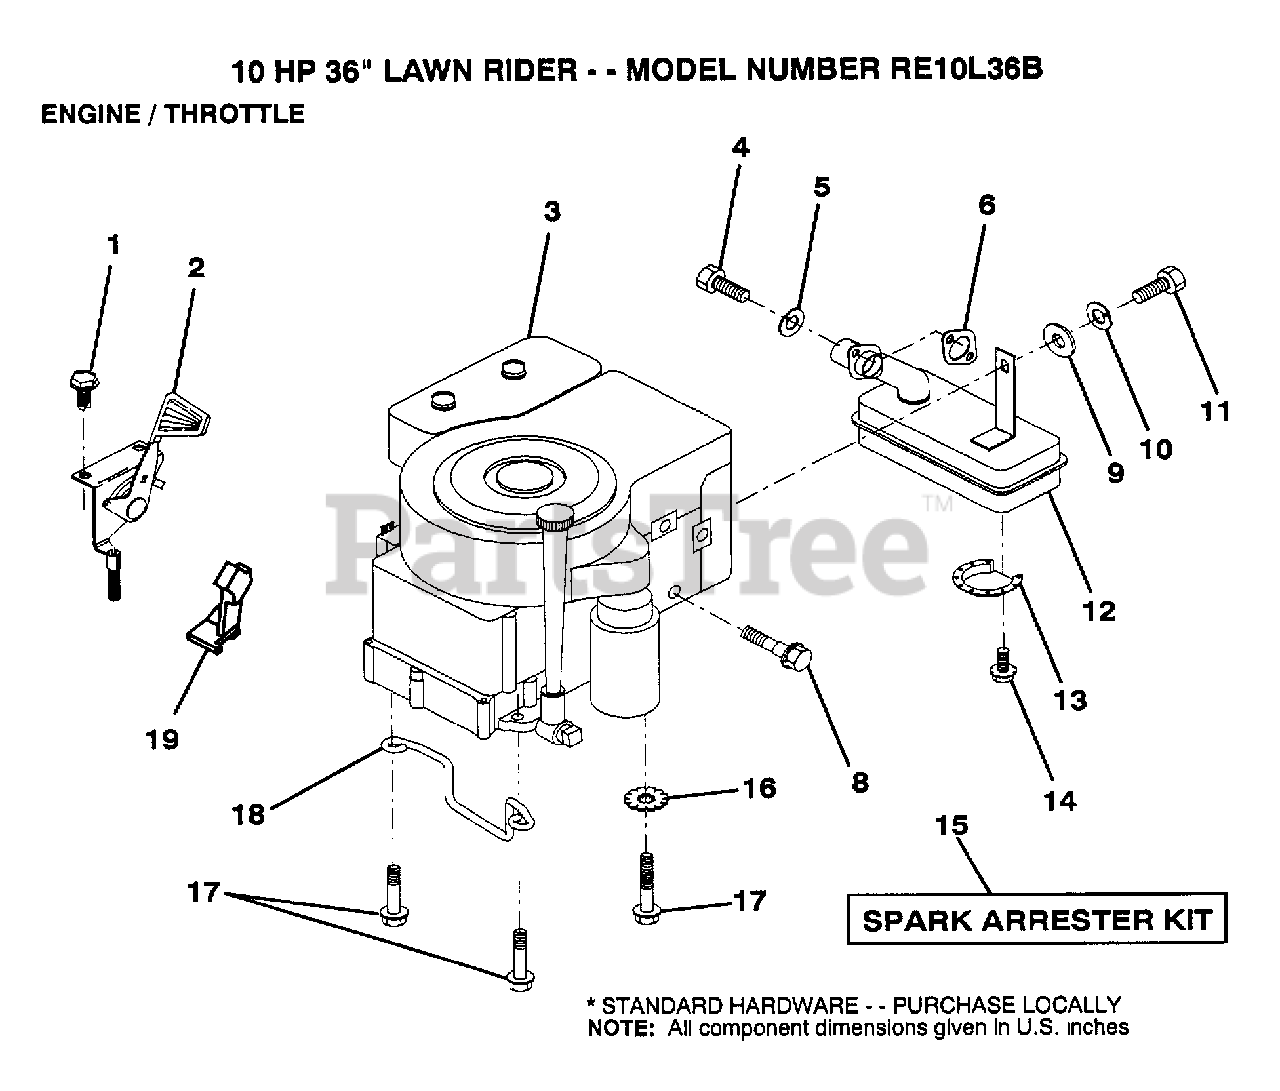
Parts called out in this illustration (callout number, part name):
1	SCREW
3	ENGINE BRIGGS AND STRATTON
4	SCREW
5	LOCKWASHER
8	BOLT T
10	LOCKWASHER
13	DEFLECTOR.222573
16	LOCKWASHER
17	SCREW LT
18	"KEEPER,DR BELT GR"
